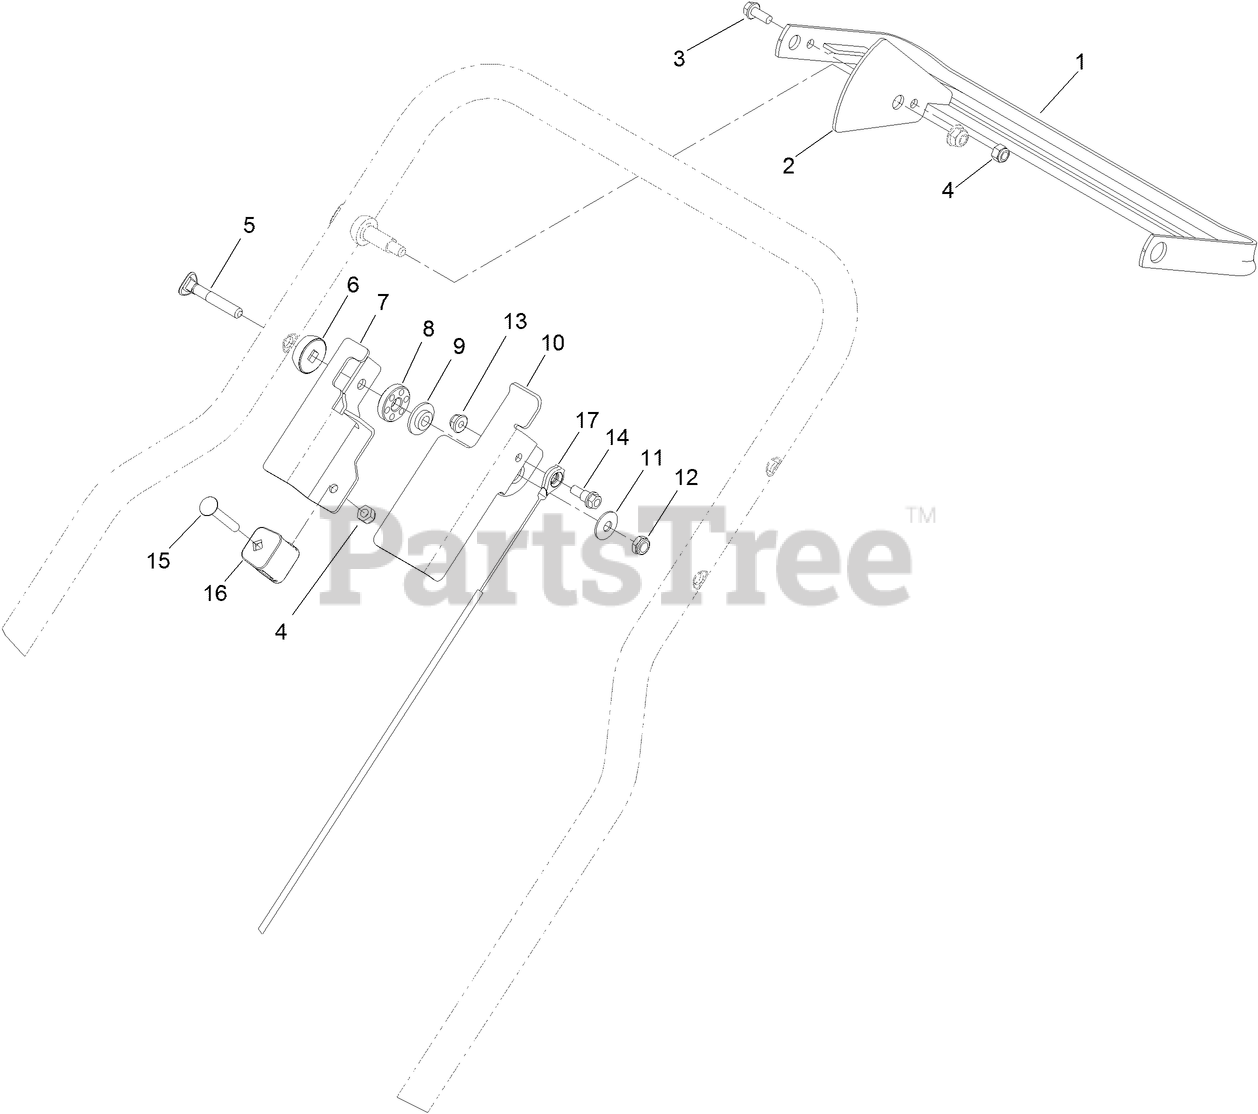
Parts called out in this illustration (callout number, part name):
1	BAR-CONTROL
3	SCREW-HWH
4	NUT-LOCK, NI
5	SCREW-HANDLE
6	WASHER-CURVED
7	BRACKET-ANCHOR, CABLE
8	WASHER
9	Washer-Stepped
10	LEVER-BRAKE
11	WASHER-BELLEVILLE
12	NUT-LOCK, NI
13	NUT-HF
14	BOLT-SHOULDER
15	SCREW-CARR
16	ANCHOR-CABLE
17	CABLE-BRAKE, PARKING
